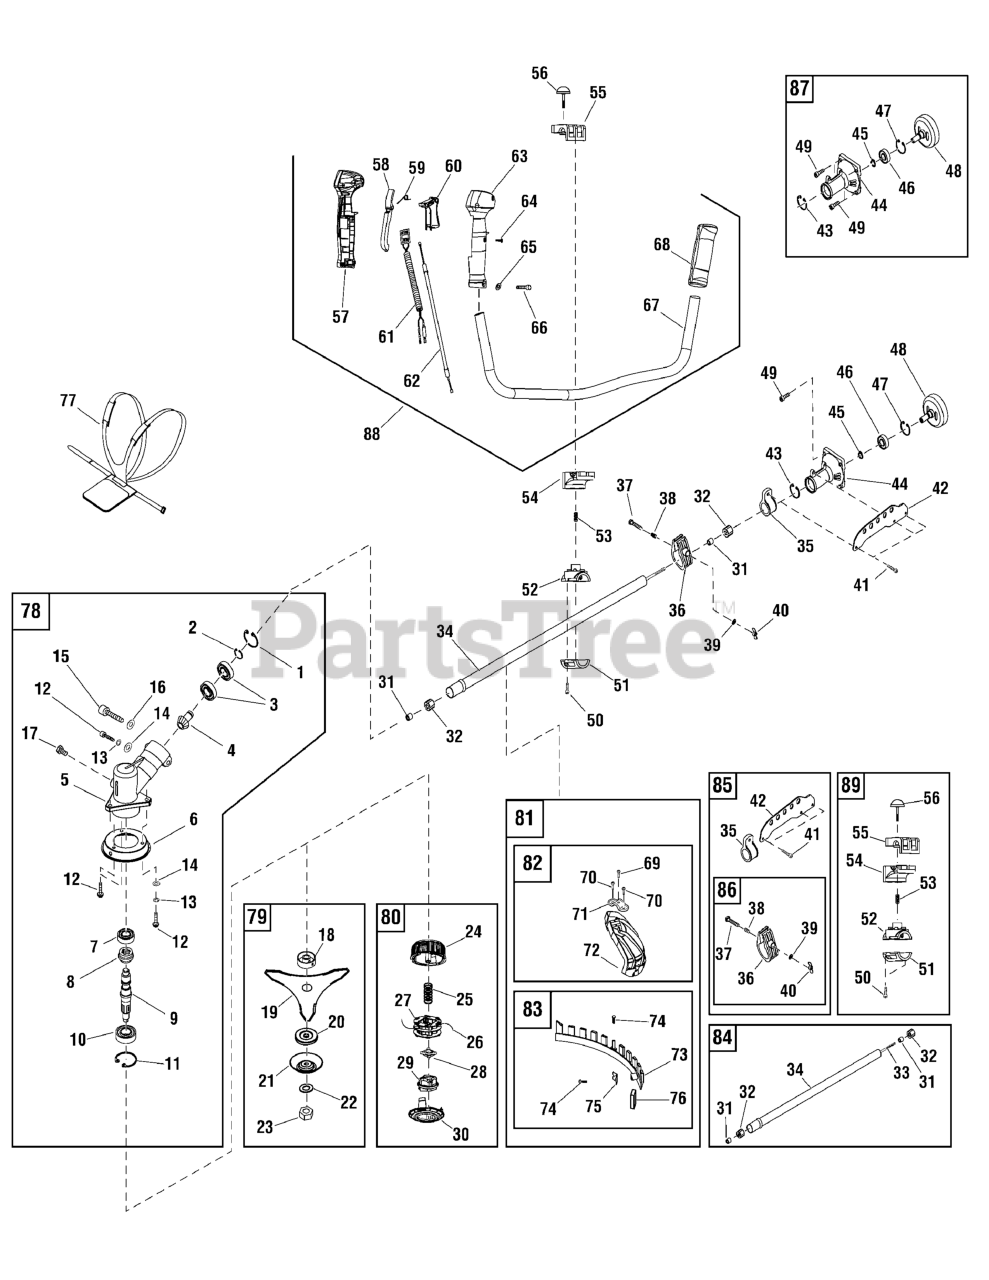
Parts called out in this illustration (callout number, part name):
4	PINION
5	GEAR BOX
6	COVER, Blade
9	SHAFT, Spline
12	BOLT, M5 x 12
13	WASHER, Spring, 5
14	WASHER, Flat, 5
15	BOLT, M6 x 20
16	WASHER, Spring, 6
18	GASKET, Spline
20	HOLDER
21	PROTECTOR, Blade
22	WASHER, Wave, 10
24	BOX, Bump Head
25	SPRING, Bump Head
26	ROPE, Flexible
27	SEAT, Flexible Rope
28	COVER, Flexible Rope
29	BUMP HEAD
30	COVER, Bump Head
31	BEARING, Oil
32	RUBBER COVER, Bearing Oil
33	DRIVE SHAFT
34	SHAFT, Straight
35	RING, Hang
36	RING, Limit
38	SPRING
41	BOLT, M6 x 16
42	HANDLE, Hang
44	CASE, Clutch
48	CLUTCH DRUM, Complete
51	BRACKET, Shaft, Lower
52	BRACKET, Shaft, Upper
53	SPRING
54	BRACKET, Handle, Lower
55	BRACKET, Handle, Upper
56	BOLT, With Knob, Red
57	COVER, Handle, Control Switch, LH
58	HANDLE, Self Lock
59	SPRING, Torsion
60	LEVEL, Throttle
61	STOP BUTTON, Complete
62	CABLE, Complete
63	COVER, Handle, Control Switch, RH
64	SCREW, Self Tapping, M3.5 x 13
65	WASHER, Flat, 5
66	SCREW, M5 x 30
67	HANDLE
68	COVER, Handle
69	BOLT, M5 x 10
70	BOLT, M5 x 12
71	HOLDER, Safety Guard
72	SAFTEY GUARD
73	SECURING SADDLE
74	SCREW, Self Tapping, ST4.2 x 16
76	COVER, Blade
77	SHOULDER BELT
78	KIT, Gear Box
79	KIT, Blade
80	KIT, Bump Head
81	KIT, Guard Assembly
82	KIT, Blade Guard
83	KIT, Securing Saddle
84	KIT, Drive Shaft
85	KIT, Hang Handle
86	KIT, Limit Ring Assembly
87	KIT, Clutch Assembly
88	KIT, Handle Assembly
89	KIT, Handle Bracket Assembly
